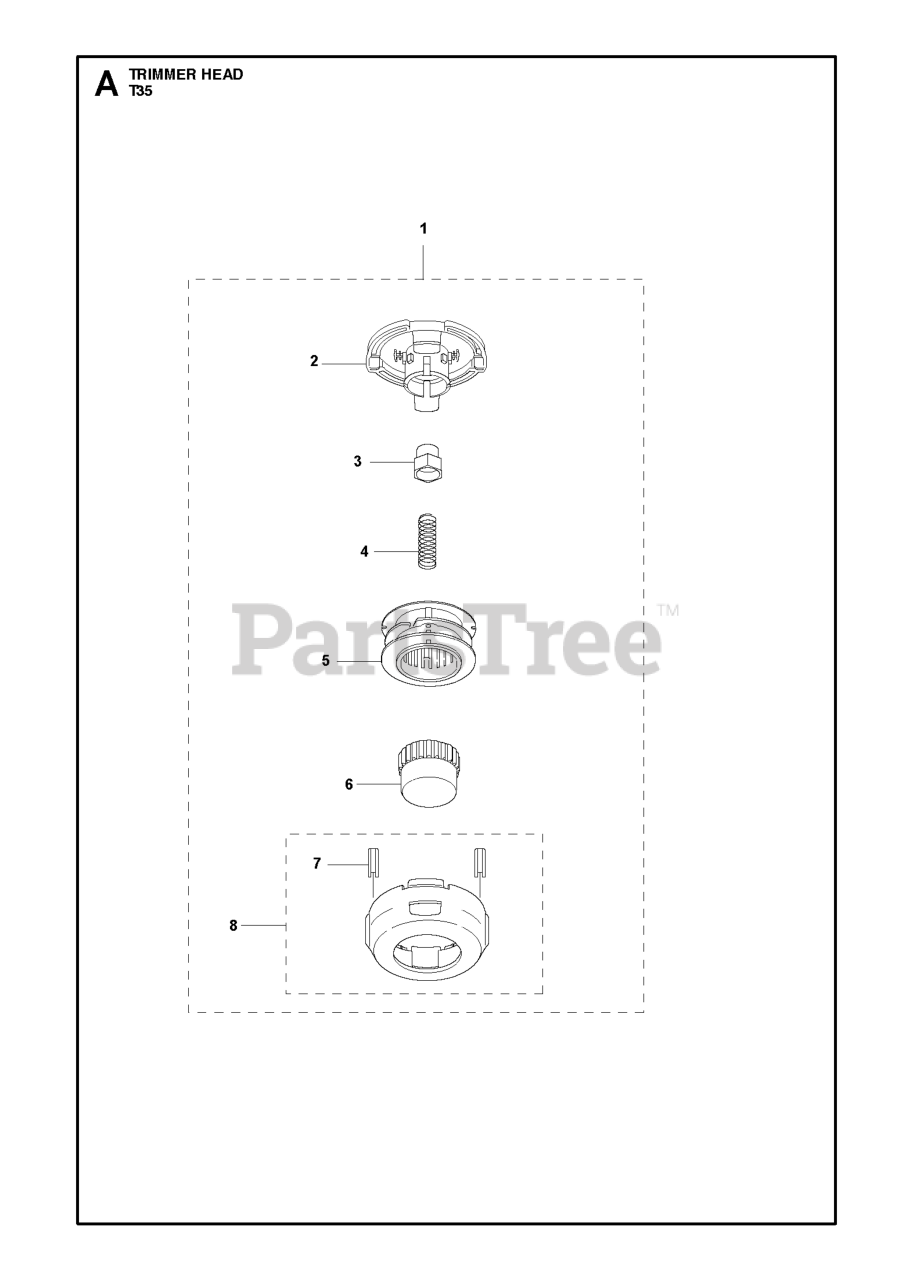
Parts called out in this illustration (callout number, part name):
1	HEAD TRIMMER T35
3	ADAPTER M10 X 1.25L
3	ADAPTOR
8	TRIMMER HEAD HOUSING
